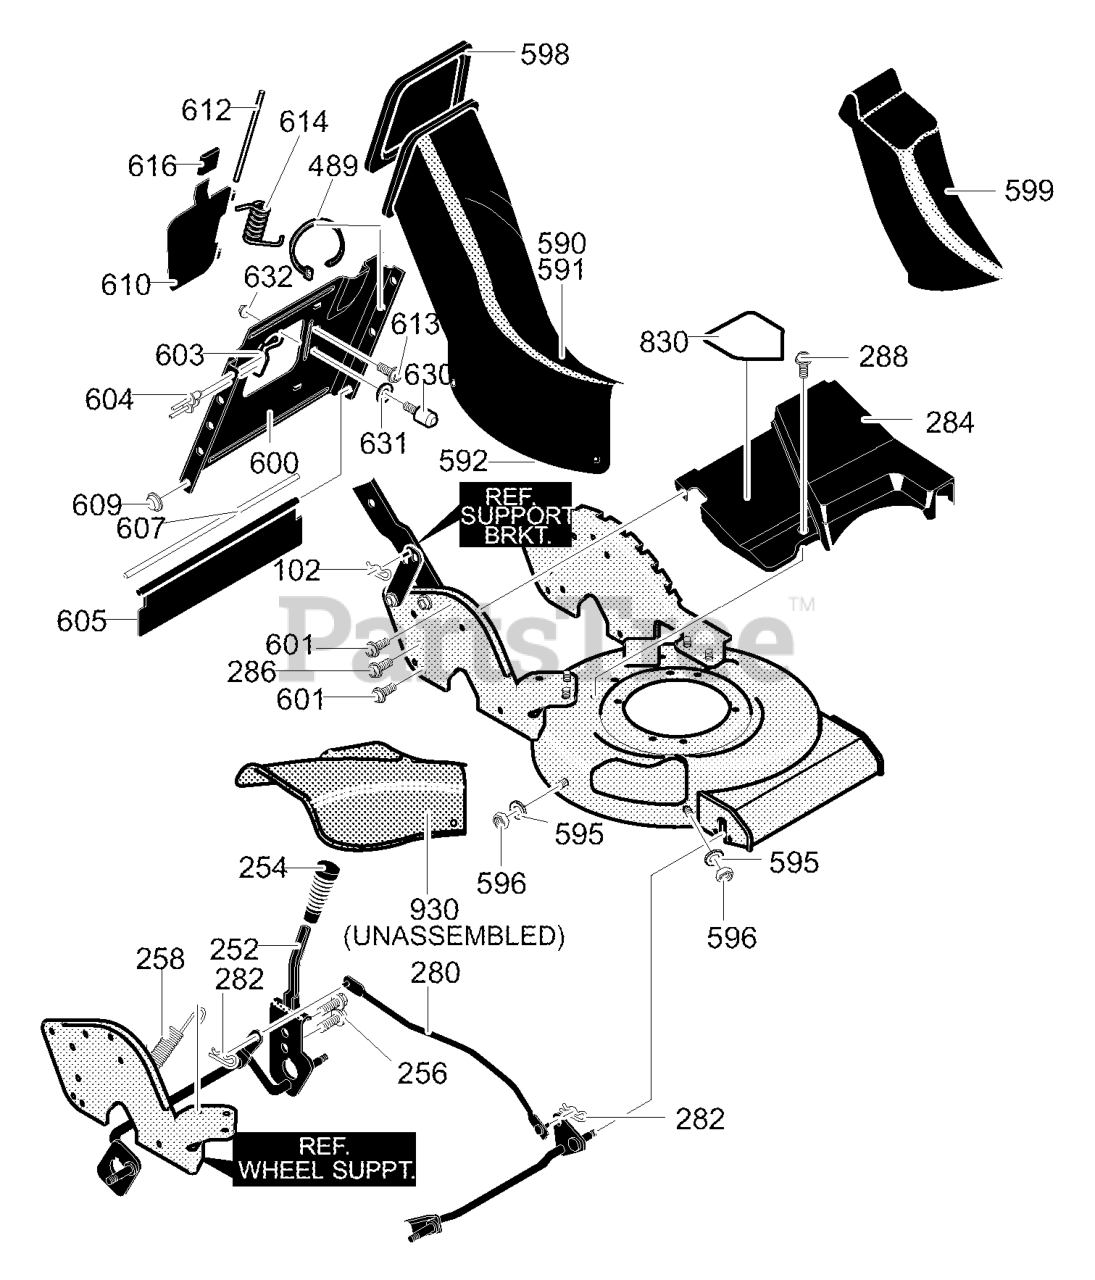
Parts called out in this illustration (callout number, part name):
102	Hair Pin
252	Spring, Lever Hgt/Adj
254	Knob, Hgt/Adj
256	Screw, 1/4-20x.63
258	Tension Spring
280	Lifter, Assy Link
282	Hair Pin
284	Rear Cover
286	Screw, 1/4-20x.63
288	Screw, 10-16x.75
489	Cable Tie
590	Chute RR Discharge
591	Chute, Floor Rear
592	Rivet, Pop
595	Flatwasher
596	Nut, 5/16-18
598	Gasket, Compression
599	Plug, Mulcher
600	Plate, Bag
601	Screw, 5/16-18 x 0.62
603	Rope Guide
604	Rivet, Pop
605	Guard, Rear Toe
607	Rod, Rear Guard
609	Cap, Push On
610	Door, Rear
612	Pin, Hinge Door
613	Screw, #8-32x.38
614	Spring, Torsion
616	Grip, Door
630	Pin, 5/16-18
631	Flatwasher
632	Nut, 5/16-18
830	Decal, Cut Finger
930	Chute, Side Discharge
